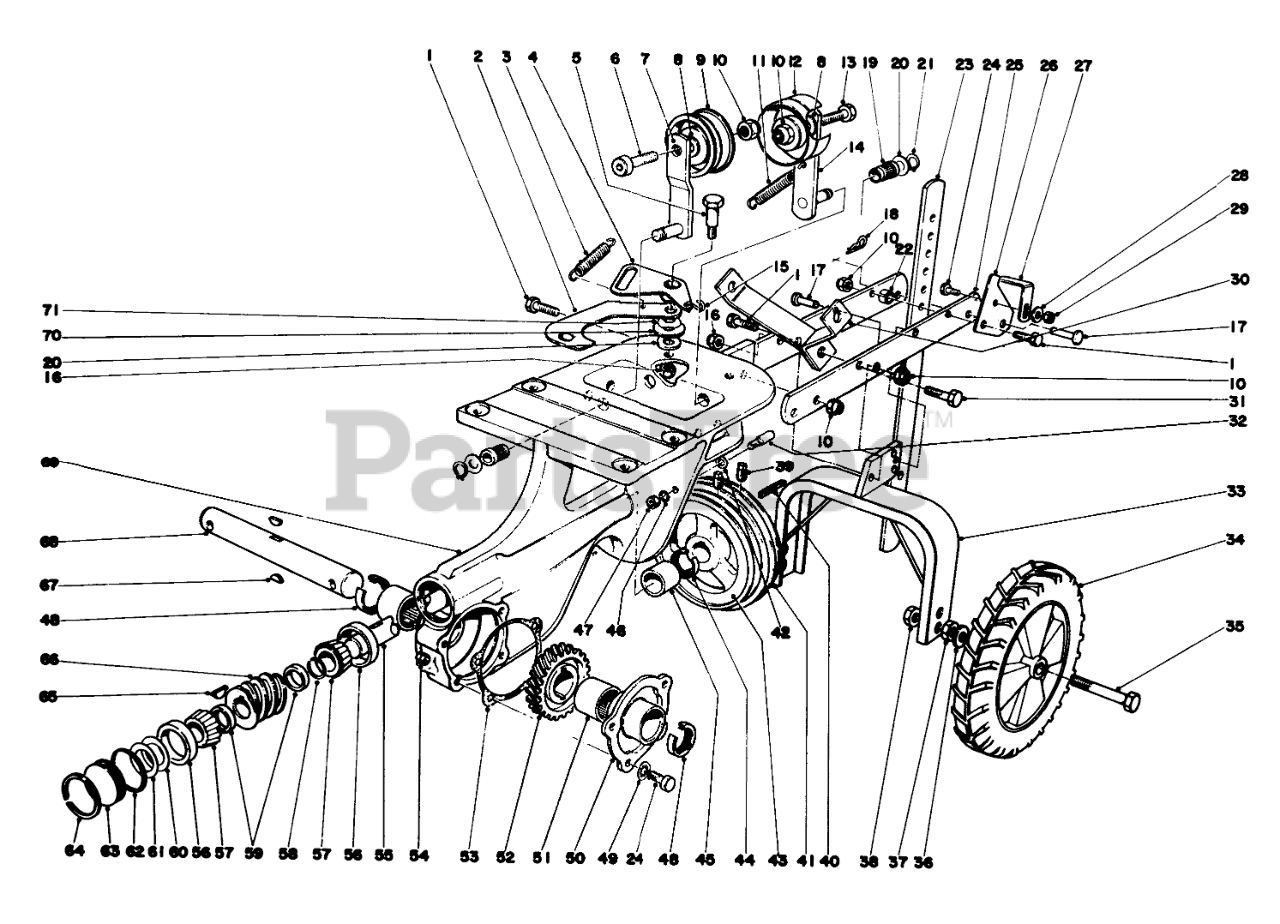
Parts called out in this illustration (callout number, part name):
1	SCREW-HH
2	Rev. Link
3	Spring
4	Bellcrank
5	SCREW-SHOULDER, HH
6	Socket Hd. Capscrew
7	IdlerArm
8	WASHER-FLAT
9	PULLEY IDLER
10	NUT-LOCK, CONE
11	Spring
12	IDLER PULLEY
13	SCREW-HH
14	Idler
15	S Hook
16	NUT-LOCK, CONE
17	TINE PIN
18	PIN-COTTER, HAIR
19	IDLER BRG
20	WASHER-PLAIN
21	RING-RETAINING, EXT
22	Spacer
23	DEPTH GAGE
24	SCREW-HH
25	Drawbar
26	Hinge Latch
27	Drag Bar Latch
28	WASHER-FLAT
29	NUT-LOCK, CONE
30	Handle Support
31	SCREW-HH
32	Belt Guide
33	Wheel Bracket
34	Wheel
35	SCREW-HH
36	WASHER-FLAT
37	NUT-JAM
38	1/2-13 CONELOCK NUT
39	SCREW-SET, HSH
40	KEY-SQUARE
41	Pulley
42	WASHER-FLAT
43	Pulley
44	SEAL-OIL
45	BUSHING
46	WASHER-LOCK/EXT
47	NUT-JAM
48	SEAL-OIL
49	WASHER-LOCK
50	Cover
51	Needle Bearing
52	WORM WHEEL
53	GASKET
54	PLUG-PIPE, SQH
55	WORM SHAFT
56	BEARING-ROLLER, CUP
57	BEARING-CONE
58	RETAINER RING
59	SPACER
62	O-RING
64	INTRNL RETAINING RING
65	KEY-WOODRUFF
66	WORM GEAR
67	KEY-WOODRUFF
68	WORM WHEEL SHAFT
69	Chassis
70	WASHER-FLAT
71	7/16 SPRING WASHER
